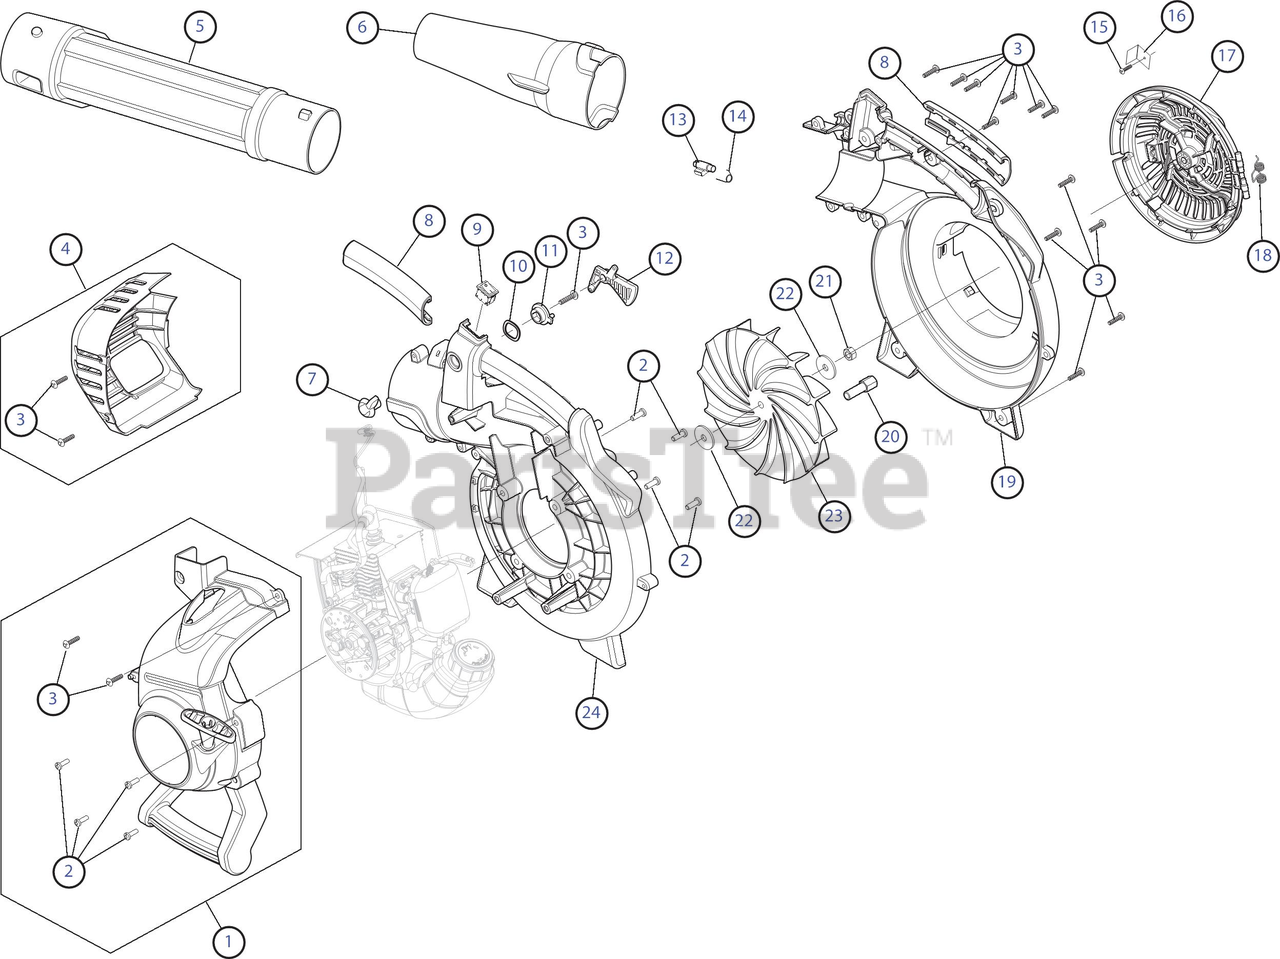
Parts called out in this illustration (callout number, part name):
1	Engine Cover Assembly (Incl. 2 & 3)
2	Screw
4	Muffler Cover Assembly (Incl. 3)
5	Upper Blower Tube
6	Nozzle
7	Outer Trigger Lock
8	Handle Grips
10	Wavey Washer
11	Inner Trigger Lock
12	Throttle Trigger
13	Latch Tube
14	Latch Spring
15	Screw
16	Door Lock
17	Intake Cover
18	Spring
19	Impeller Housing
20	Adapter
21	Nut
22	Washer
23	Impeller
24	Impeller Housing
